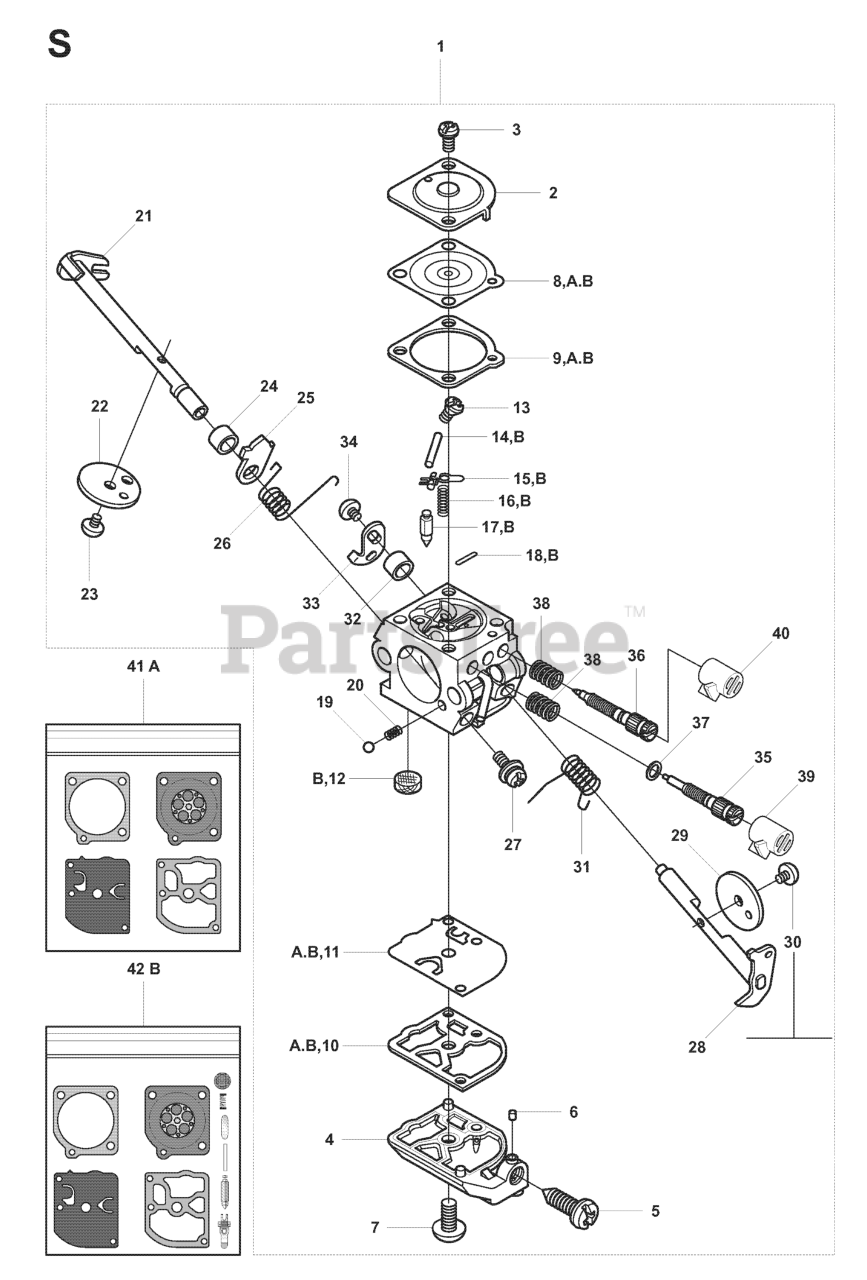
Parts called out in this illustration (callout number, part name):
1	CARBURETOR
11	PUMP DIAPHRAGM
14	PIN RETAINING SCREW
16	SPRING
17	INLET NEEDLE
29	THROTTLE FLAP
31	SPRING THROTTLE
35	NEEDLE HIGH SPEED
36	LOW SPEED NEEDLE
38	SPRING
